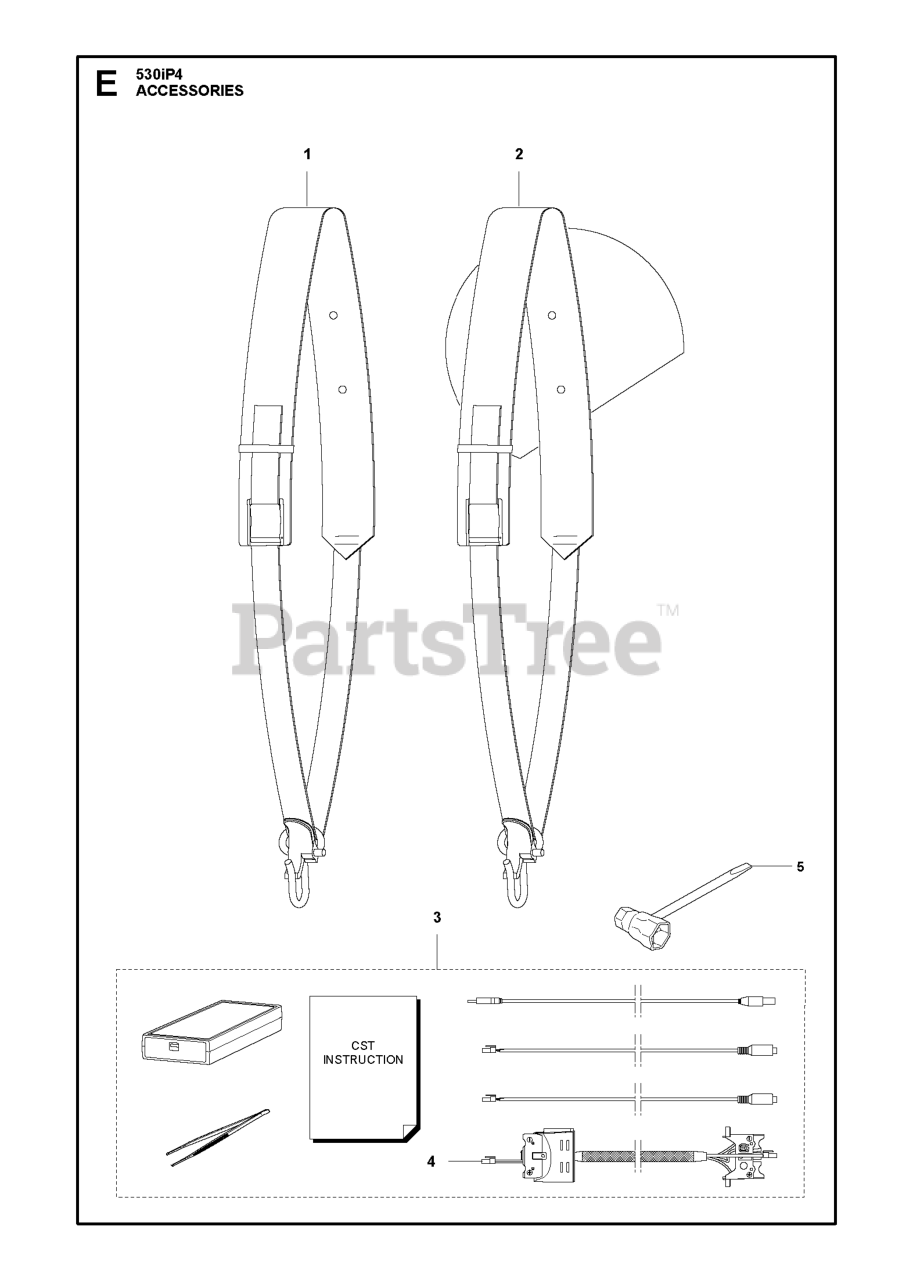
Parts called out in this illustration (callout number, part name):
1	Harness-w/o warning
2	Harness - Diagonal with sign
3	DIAGNOSTIC TOOL KIT
4	WIRING ASSY
5	COMBI TOOL
